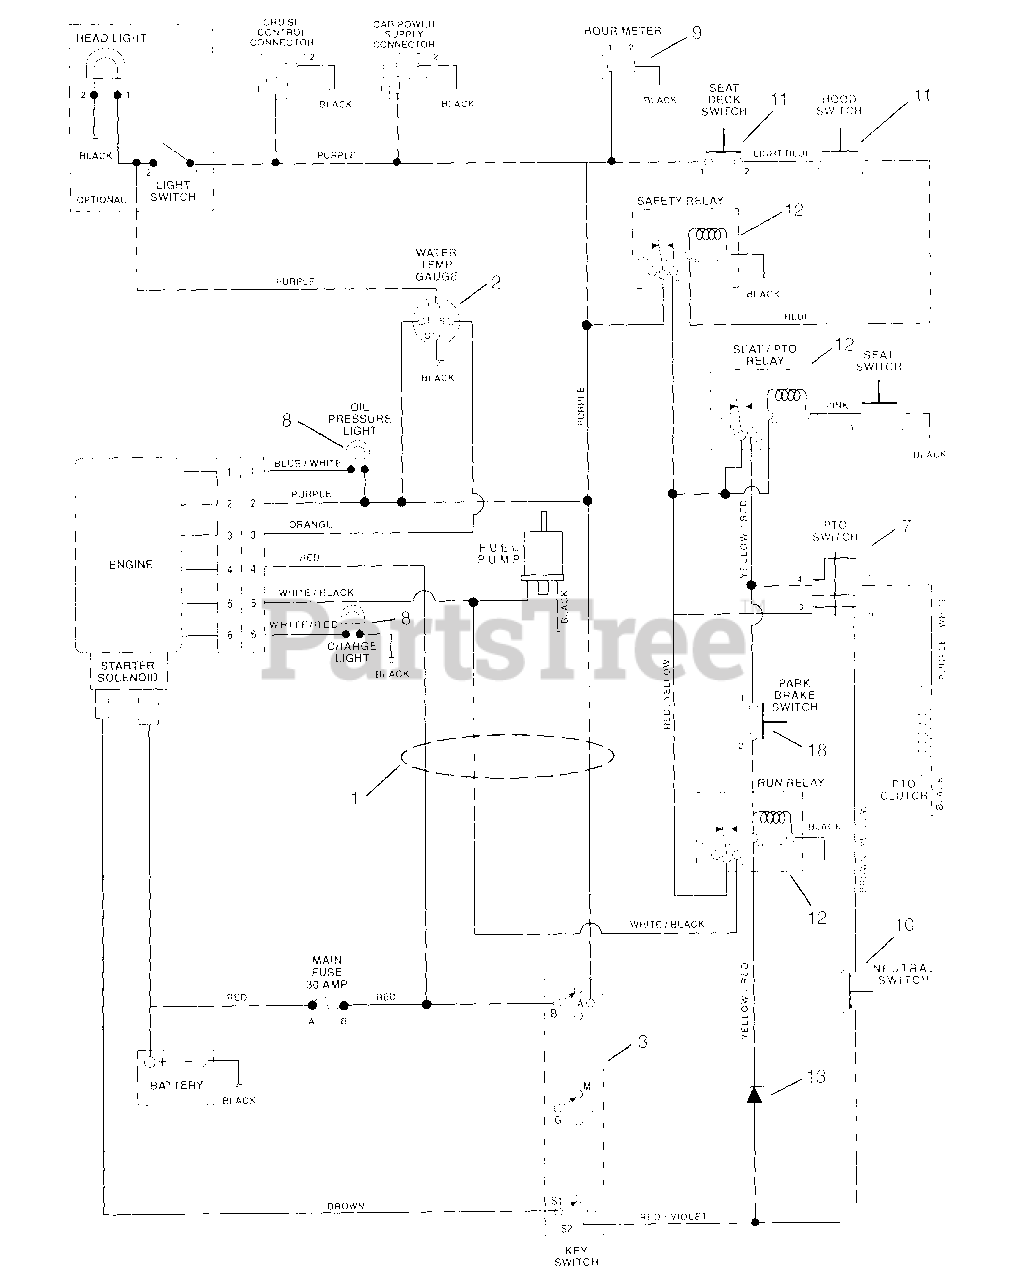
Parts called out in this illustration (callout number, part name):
1	Harness, Wiring
2	Gauge, Temperature
3	Switch, Ignition
4	Cap, Ignition Switch
5	Ignition Key Set
6	Key Chain
7	Switch, Clutch with Retaining Ring
8	Light, indicator
9	Hour Meter
10	Switch, Neutral N.C.
11	Switch, Interlock
12	Relay
15	Fuse 30 Amp
16	Temperature Sender
18	Switch, Interlock N.C.
